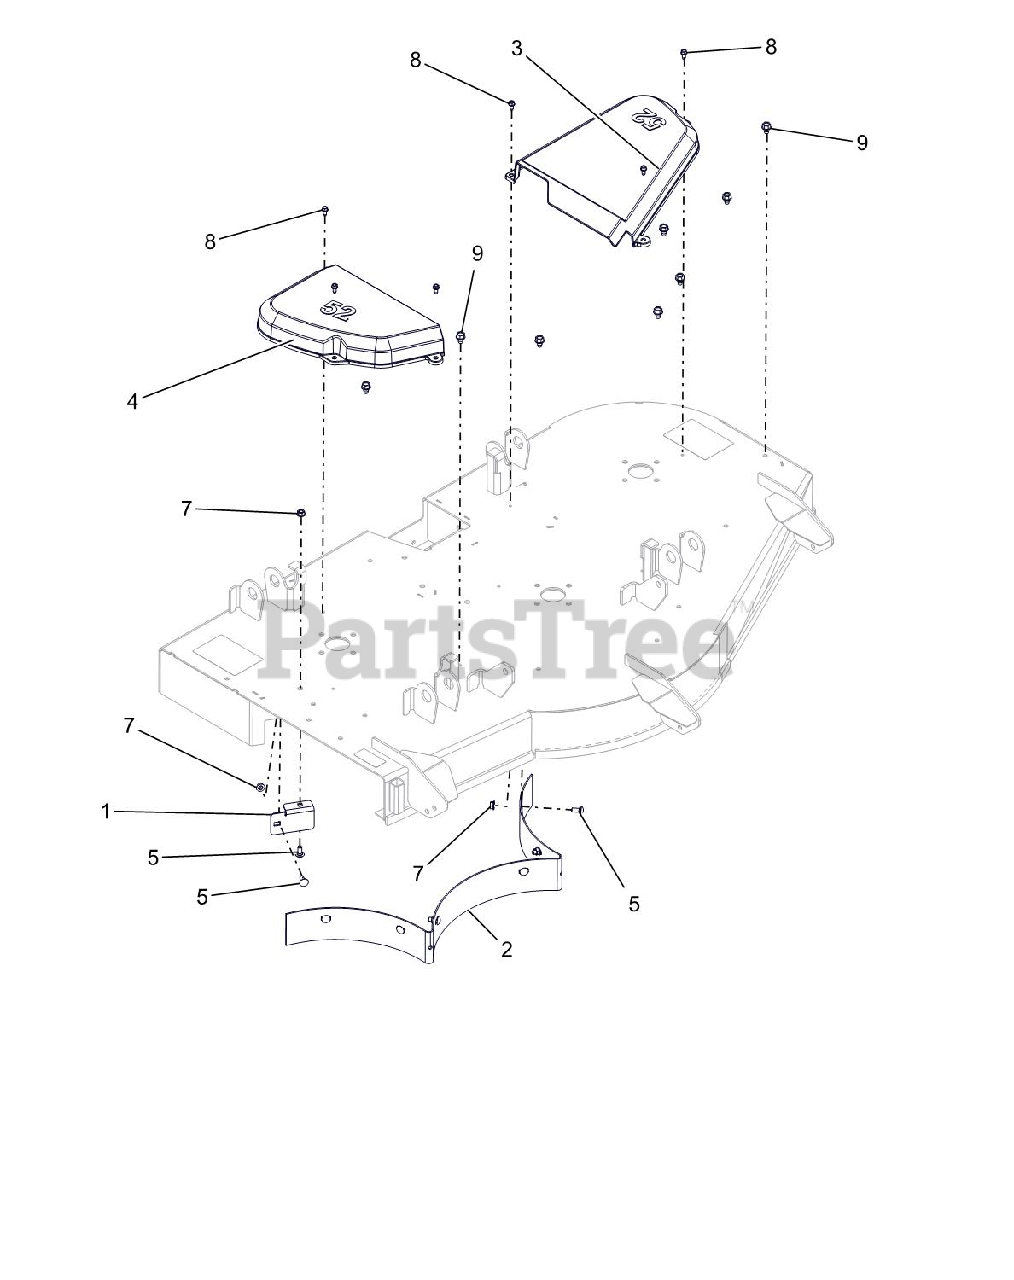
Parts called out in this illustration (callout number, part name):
1	STRIP, DEFLECTOR - 52"
2	BAFFLE, REAR - REMOVABLE 52"
3	COVER, BELT 52" LH
4	COVER, BELT 52" RIGHT
5	@BLT-RDHDSQNK .31-18X.75 G5YZ
7	NUT-LK-TOP-FLG .31-18 YWZC
8	SCR-TAP .25-20X.50 HWH TR YWZ
9	@SCR-TAP .38-16X.50 HWH TR YWZ
